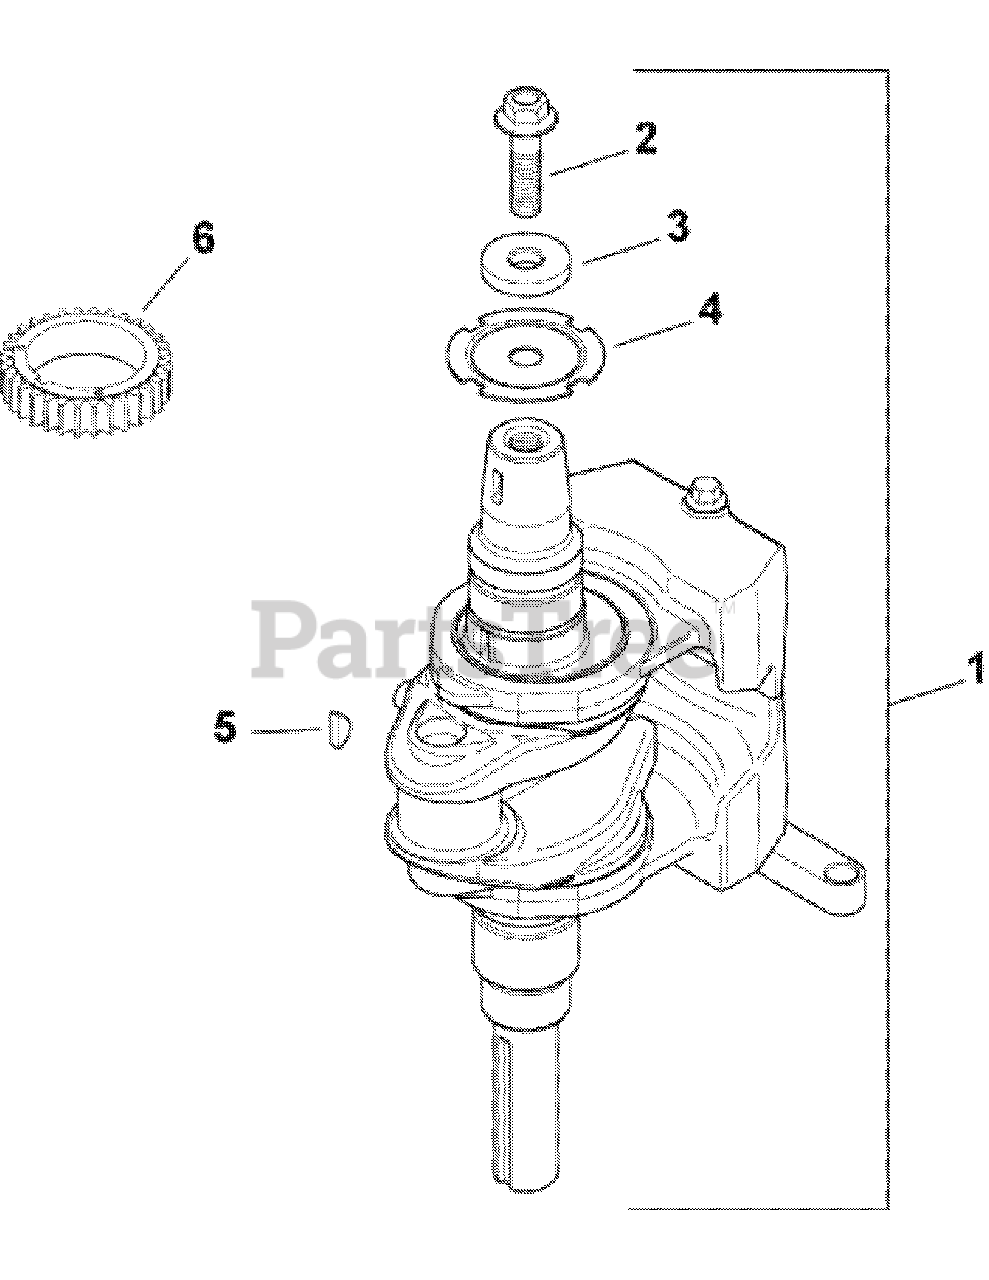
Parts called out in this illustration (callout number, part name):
1	KIT, CRANKSHAFT
2	SCREW, HEX FLANGE
3	WASHER, FLAT
4	PLATE, FAN MOUNTING
5	KEY, 3/16" X 5/8"
6	GEAR, CRANKSHAFT
